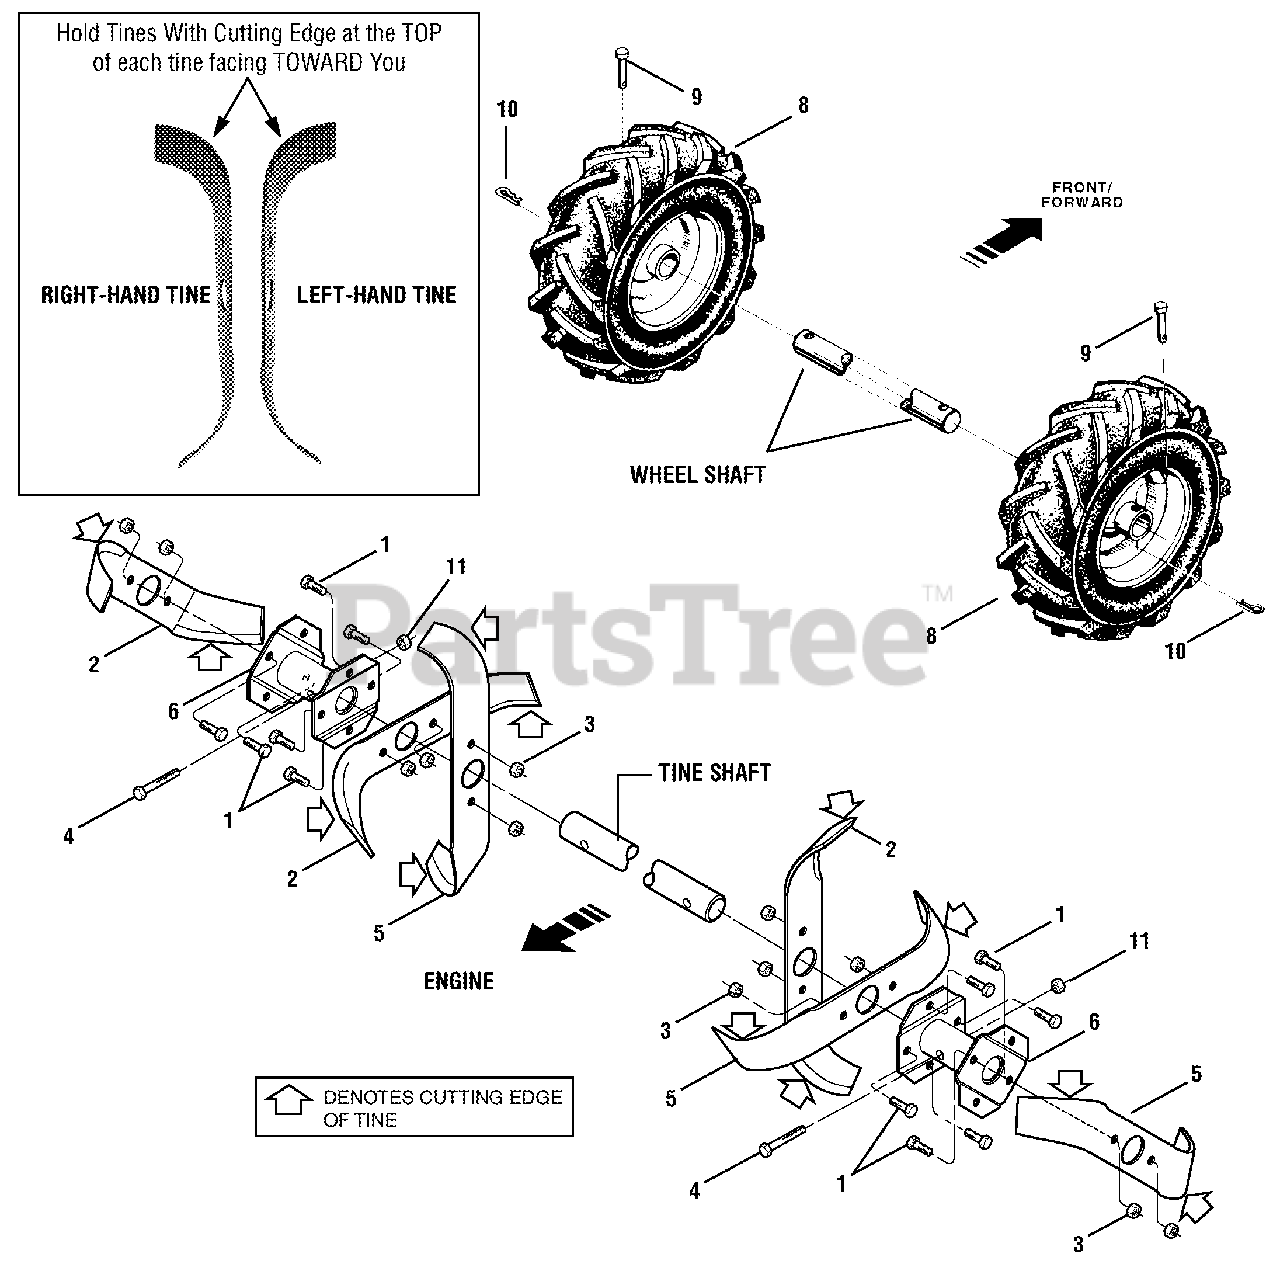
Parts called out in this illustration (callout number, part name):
1	Hex Hd. Screw, 5/16-18 x 3/4, Grade 5
2	Single Tine - Right Hand
3	Hex Lock Nut, 5/16-18
4	Hex Hd. Screw, 3/8-16 x 2
5	Single Tine - Left Hand
6	LH Tine Holder
8	Wheel & Tire Ass'y - Left/Right Side
9	Clevis Pin, .312" x 1-3/4"
10	Hair Pin Cotter
11	Hex Lock Nut, 3/8-16
